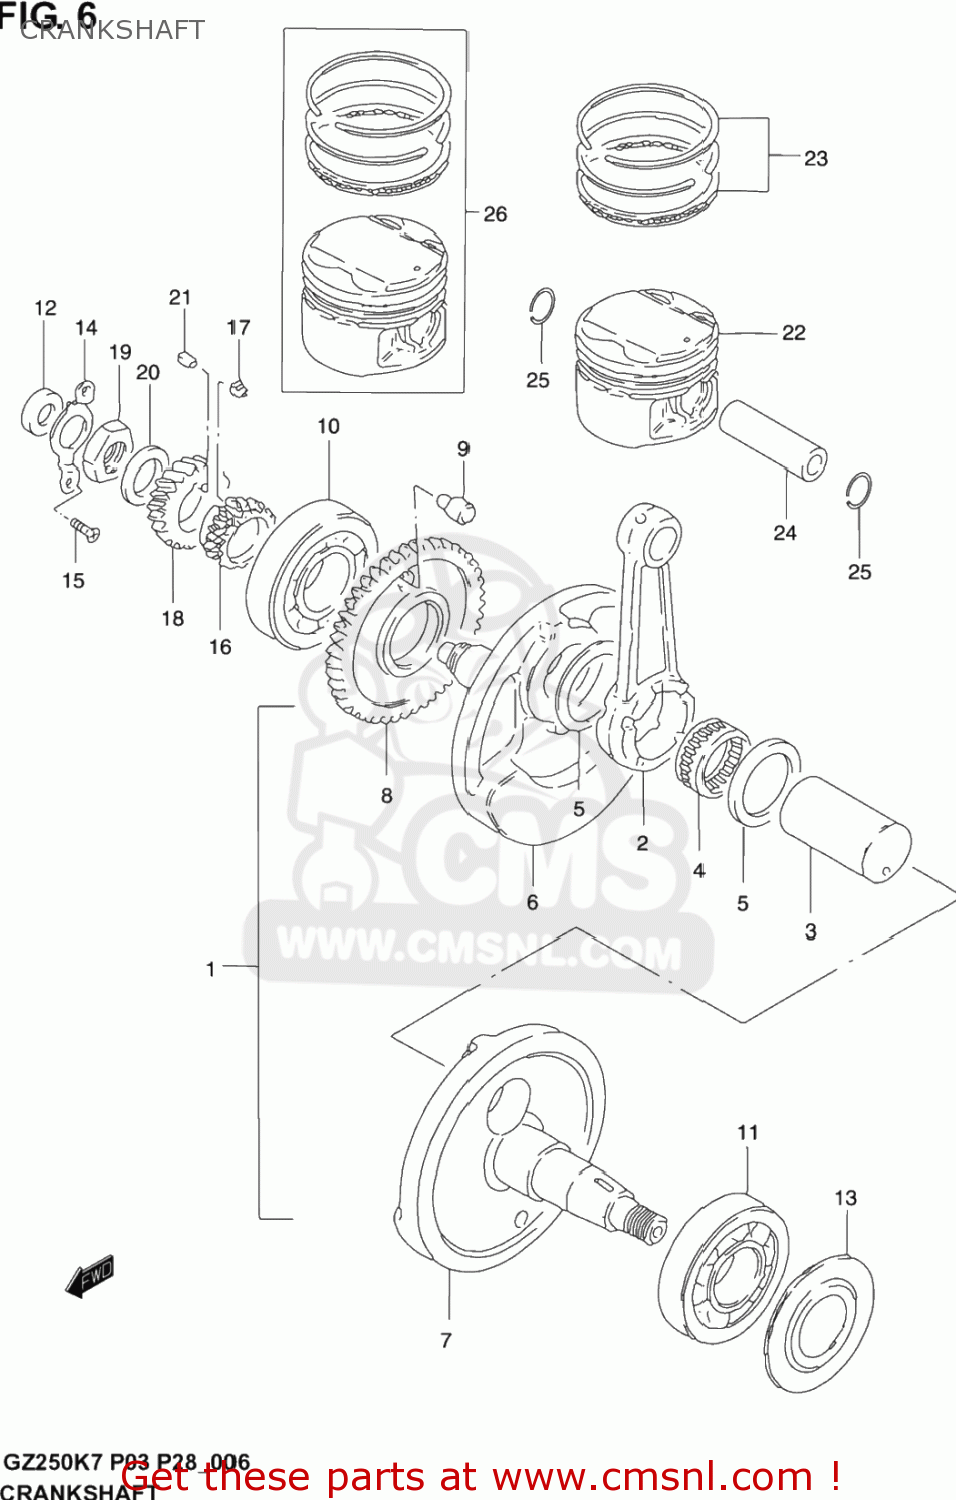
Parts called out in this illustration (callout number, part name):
1	CRANKSHAFT ASS
2	ROD,CONNECTING
3	PIN,CRANK
4	BEARING(31X39X21)
5	WASHER(31X48.5X1)
6	CRANKSHAFT,R
7	CRANKSHAFT,L
8	GEAR,CRANK BALANCER DRIVE
9	PIN
10	BEARING(30X72X19)
11	BEARING(35X80X21)
12	SEAL,OIL(14X26X6)
13	WASHER,CRANKSHAFT OIL SEALING
14	RETAINER,CRANKSHAFT BEARING,R
15	SCREW
16	SPROCKET,CAM CHAIN DRIVE(NT:21
17	KEY,SPROCKET
18	GEAR,PRIMARY DRIVE NO.21
19	NUT (20MM)
20	WASHER
21	KEY
22	PISTON
23	RING SET,PISTON
24	PIN,PISTON
25	CIRCLIP
26	PISTON SET(OS:0.5)
